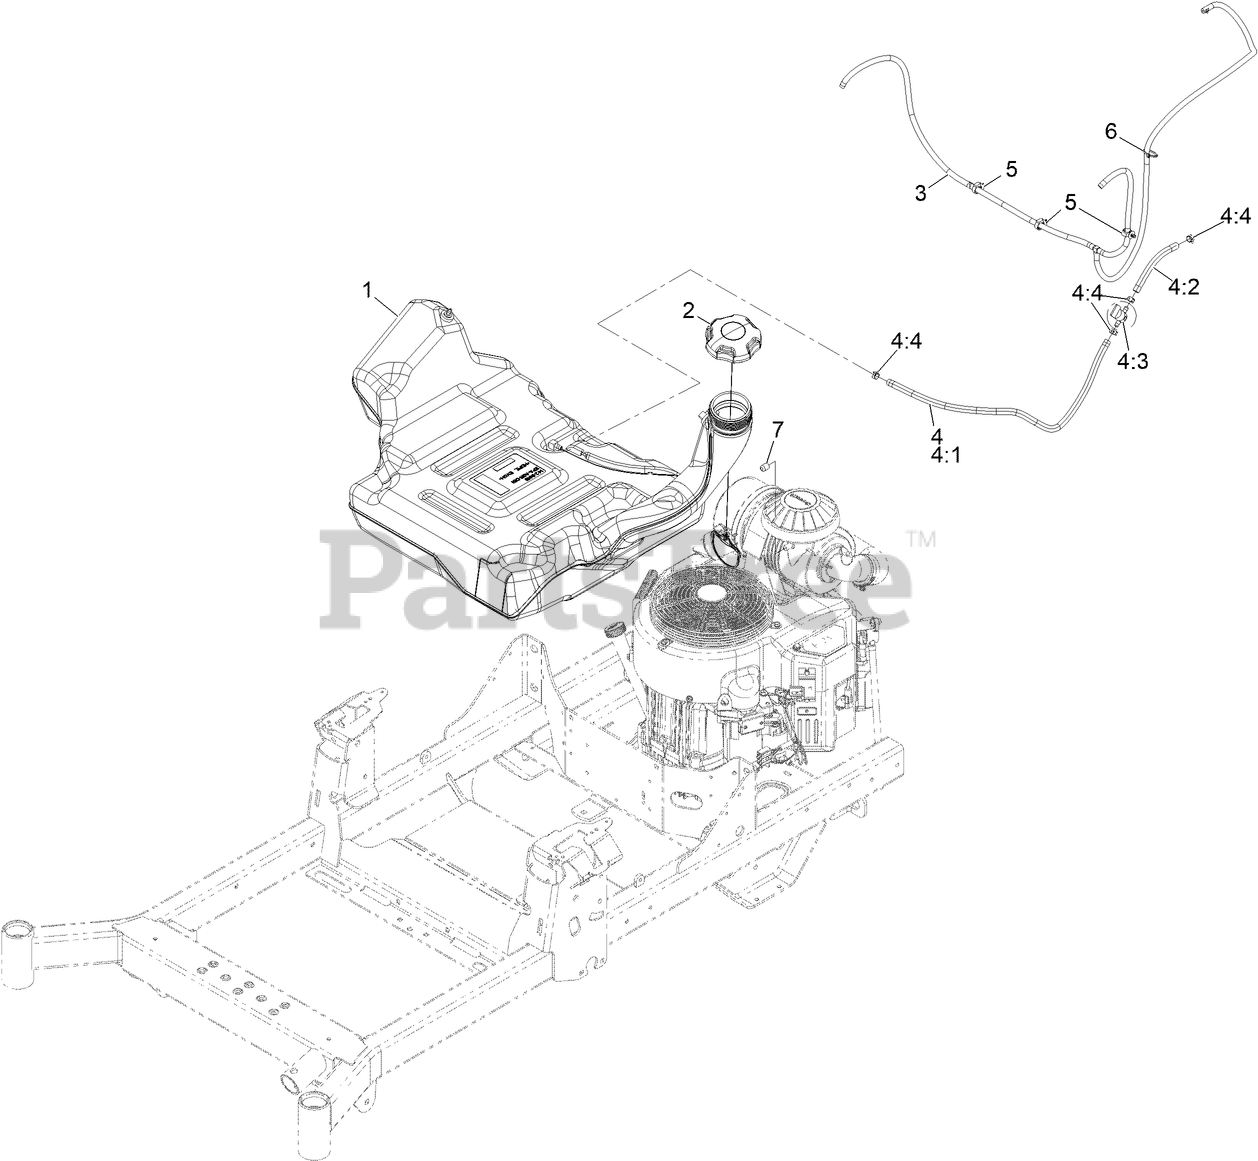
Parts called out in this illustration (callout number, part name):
1	ASM-FUEL TANK
2	CAP-FUEL, RATCHETING
3	Vent Hose ASM
4	FUEL HOSE ASM
4:1	HOSE-FUEL
4:2	HOSE-FUEL
4:3	VALVE-FUEL
4:4	CLAMP-HOSE
6	TIE-CABLE
7	PLUG-PORT
